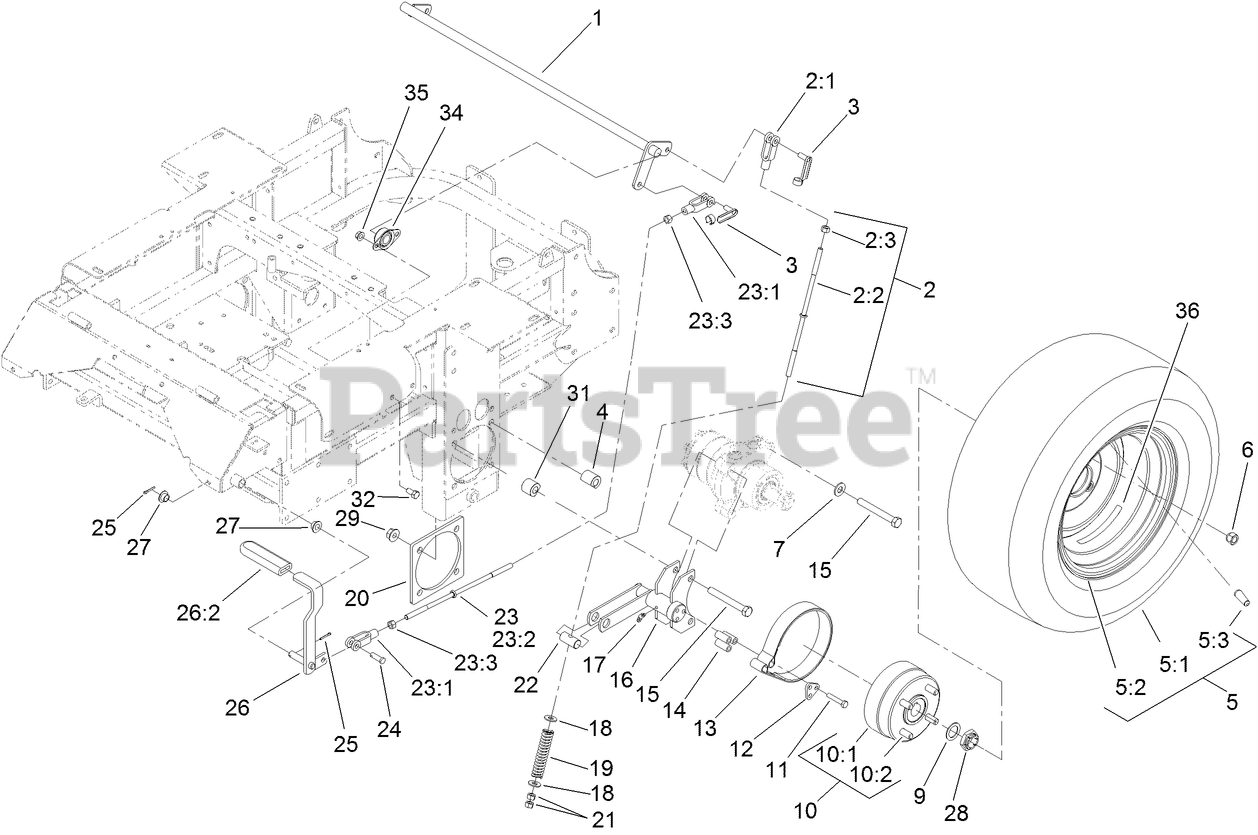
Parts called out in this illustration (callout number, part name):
1	SHAFT-BRAKE
2	BRAKE ROD ASM
2:1	YOKE-LINKAGE, BRAKE
2:2	ROD-BRAKE
2:3	NUT-HEX
3	PIN-SPRING, CLEVIS
4	SPACER-WHEEL, LONG
5	WHEEL AND TIRE ASM
5:1	TIRE
6	NUT-LUG
7	WASHER-THRUST
9	WASHER-SPACER
10	WHEEL HUB ASM
10:1	HUB-WHEEL
10:2	STUD-WHEEL
11	SCREW-HH
12	RETAINER-BAND, BRAKE
13	BAND-BRAKE
14	SPACER
15	SCREW-HH
16	BRACKET-BRAKE
17	FITTING-GREASE
18	WASHER-FLAT
19	SPRING-BRAKE
20	PLATE-REINFORCEMENT
21	NUT-HEX
22	PIN-TRUNION
23	BRAKE ROD ASM
23:1	YOKE-LINKAGE, BRAKE
23:2	ROD-BRAKE
23:3	NUT-HEX
24	PIN-CLEVIS
25	PIN-COTTER
26	BRAKE LEVER ASM
26:2	GRIP-LEVER
27	BEARING-CONTROL
28	LOCKNUT
29	NUT-HHF
31	SPACER-WHEEL, SHORT
32	SCREW-HH
34	BEARING-FLANGE, SIDE
35	NUT-HHF, WHIZ
36	DECAL-TORQUE, WHEEL HUB LUG
